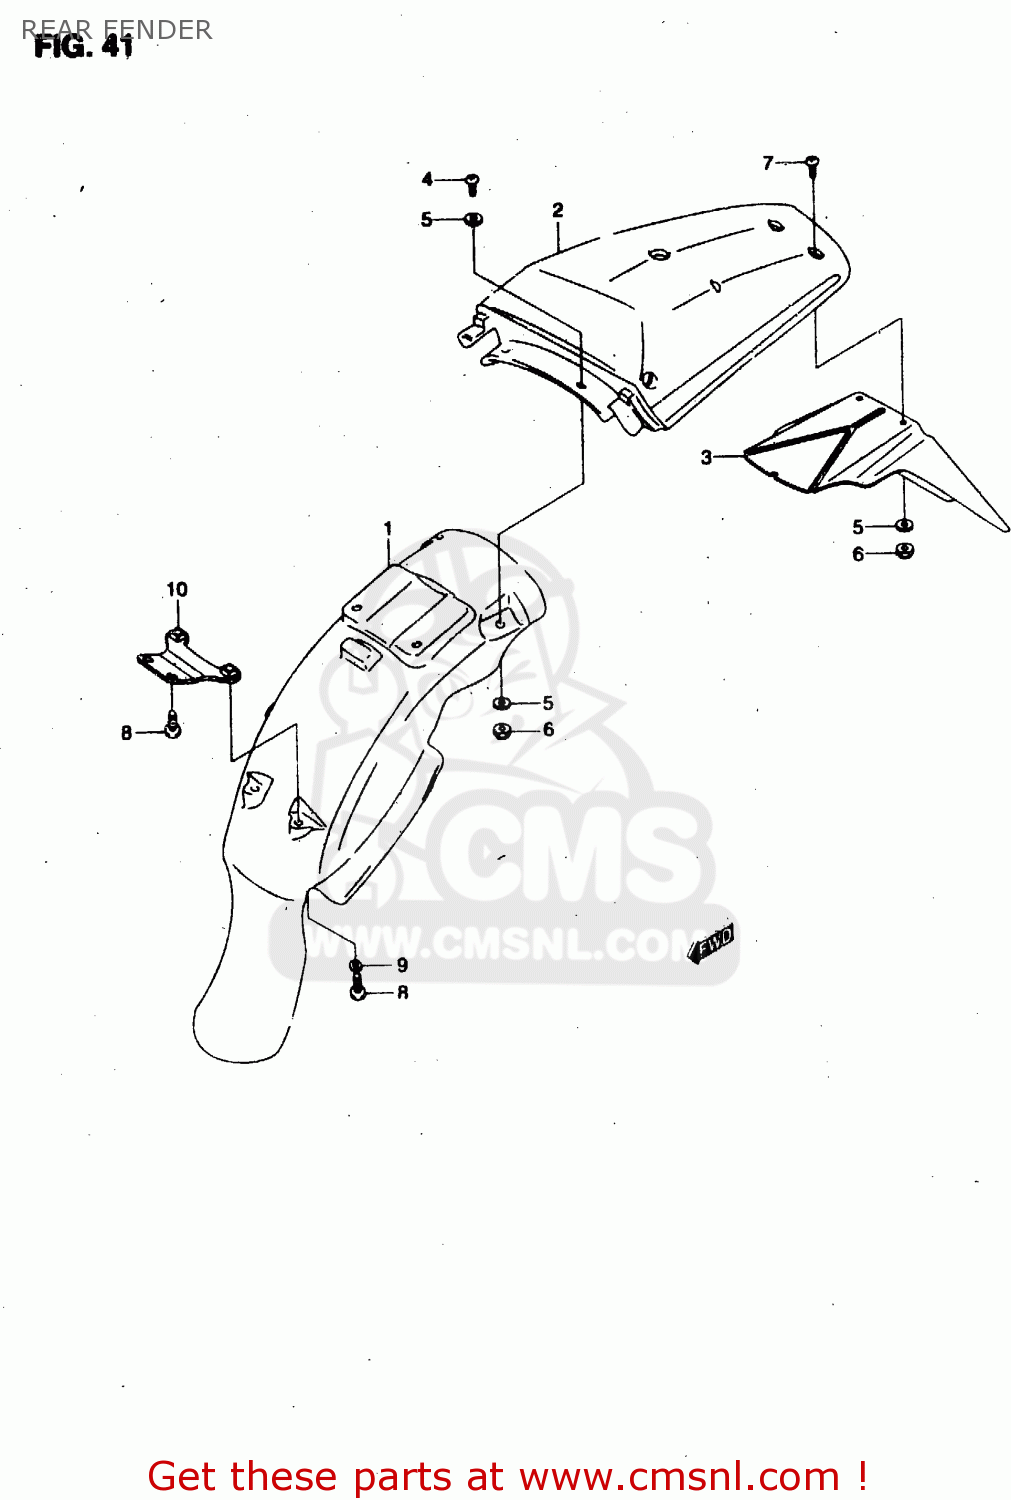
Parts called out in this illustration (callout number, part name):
1	BODY, REAR FENDER FRONT
2	BODY REAR, REAR FENDER (WHITE)
3	EXTENSION, REAR FENDER
4	SCREW
5	WASHER (5.5X18X1)
6	NUT
7	SCREW
8	SCREW
9	WASHER
10	BRACKET
